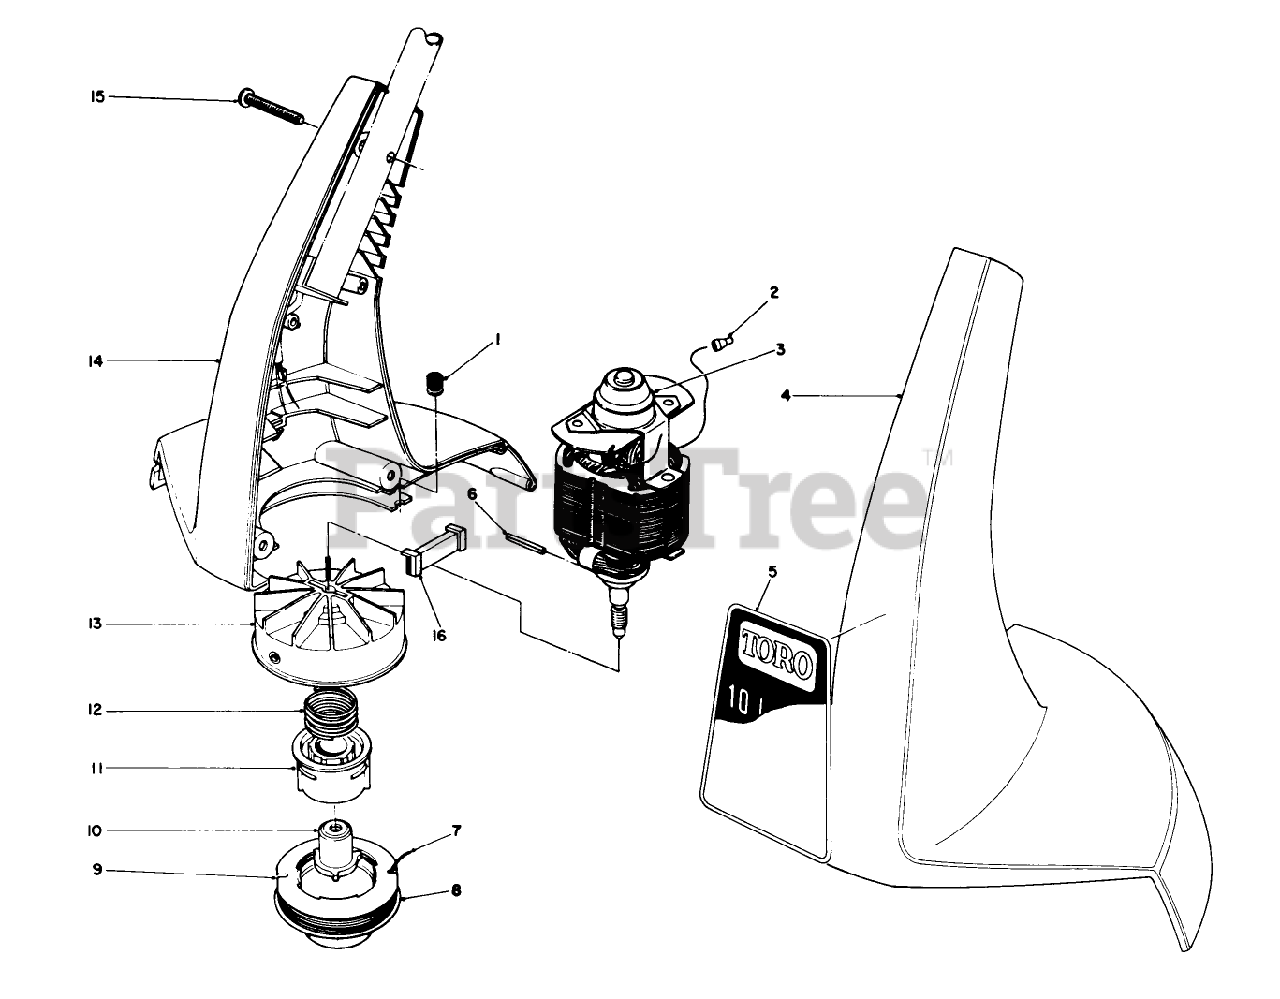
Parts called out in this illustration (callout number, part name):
1	GROMMET
2	CONNECTOR WIRE JOINT
3	Motor
4	LH HOUSING - 1010 TRIM
5	DECAL, 10" TRIMMER
6	COIL PIN
7	Line-Cutting (30- .05 Dia.)
8	SPOOL CAP
9	Prewound Spool Cap
10	DRIVER DETENT
11	CORE - SPOOL
12	SPRING-COMPRESSION
13	FAN HUB ASM
14	HOUSING ASSEMBLY-RH
15	Screw
16	INSERT - HOUSING
